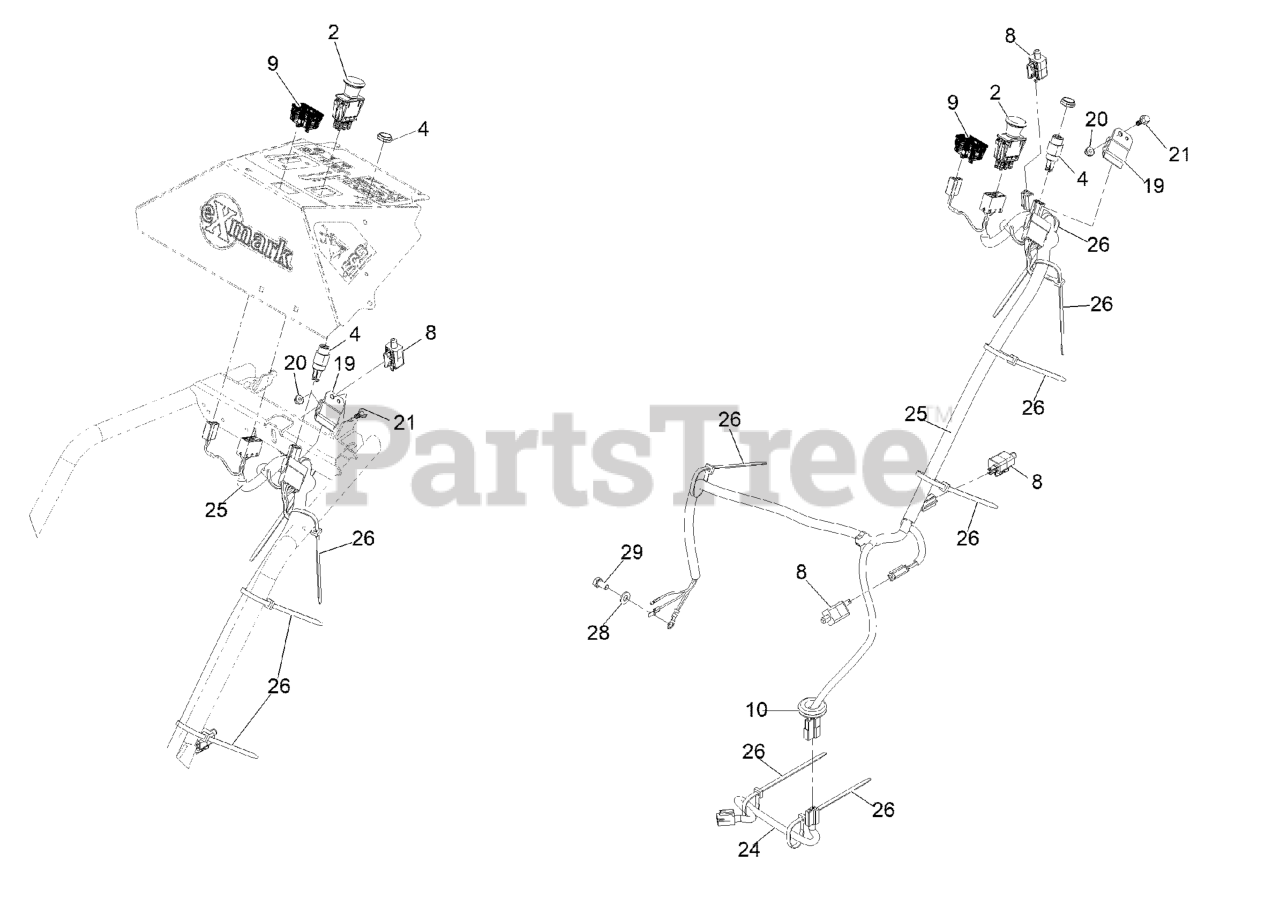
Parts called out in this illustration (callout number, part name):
2	SWITCH-PTO
4	SWITCH & KEY (INCLUDES NU
4	NUT-SWITCH, IGNITION
9	METER-HOUR
10	GROMMET
19	MODULE-INTERLOCK
21	SCREW-HHF
24	HARNESS-CLUTCH PIGTAIL
25	HARNESS-MAIN
26	TIE-CABLE
28	WASHER-PLAIN
29	SCREW-HH
